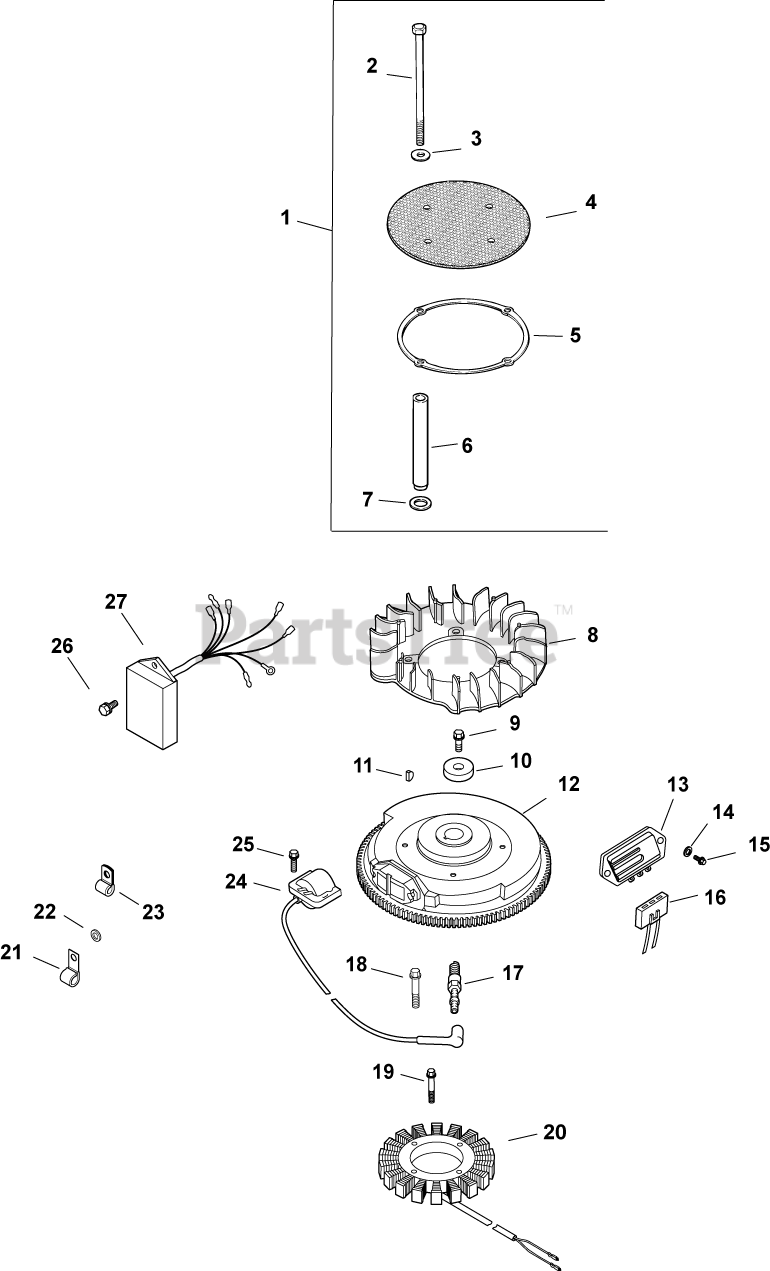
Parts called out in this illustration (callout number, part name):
1	KIT, CHOPPER SCREEN
2	SCREW, CAP M6X1.0X99.5
3	WASHER, FLAT 1/4" (O.D. 5/8")
4	SCREEN, GRASS
5	RING, SUPPORT USE 25 141 08-S
7	WASHER, SPRING 10 MM
9	SCREW, FLG M10X1.5X45 - (#25086361S)
10	WASHER, FLAT 13/32"
11	KEY, 3/16" X 5/8"
12	FLYWHEEL ASSEMBLY-USE 24 025 58-S
13	REG/RECT-15 AMP (KM)-USE 41 403 10-S
14	WASHER, FLAT 3/16"
15	SCREW, PHL HD #11-16X7/8"
16	CONNECTOR, BODY (KM)-USE 25 155 41-S
17	PLUG, SPARK (PRO SERIES)
18	SCREW, M5X0.8X25 - (#25086402S)
19	SCREW, SKT SET #10-24X1/4"
20	KIT, 15 / 20 AMP STATOR
21	CLIP, TUBE & WIRING (KM)
22	WASHER, FLAT 1/4" (O.D. 1/2")
23	CLIP, CABLE
24	MODULE, IGNITION
25	SCREW, FLG THD FRM M5X.8X20-(#25086399S)
26	SCREW, THD FRM M4X0.7X10
27	MODULE, SPEED ADVANCE (DSAM) - DISCONTINUED SEE PB 259
2458453-S	MOD SPARK ADV (DSAI) -USE 24 584 64-S
